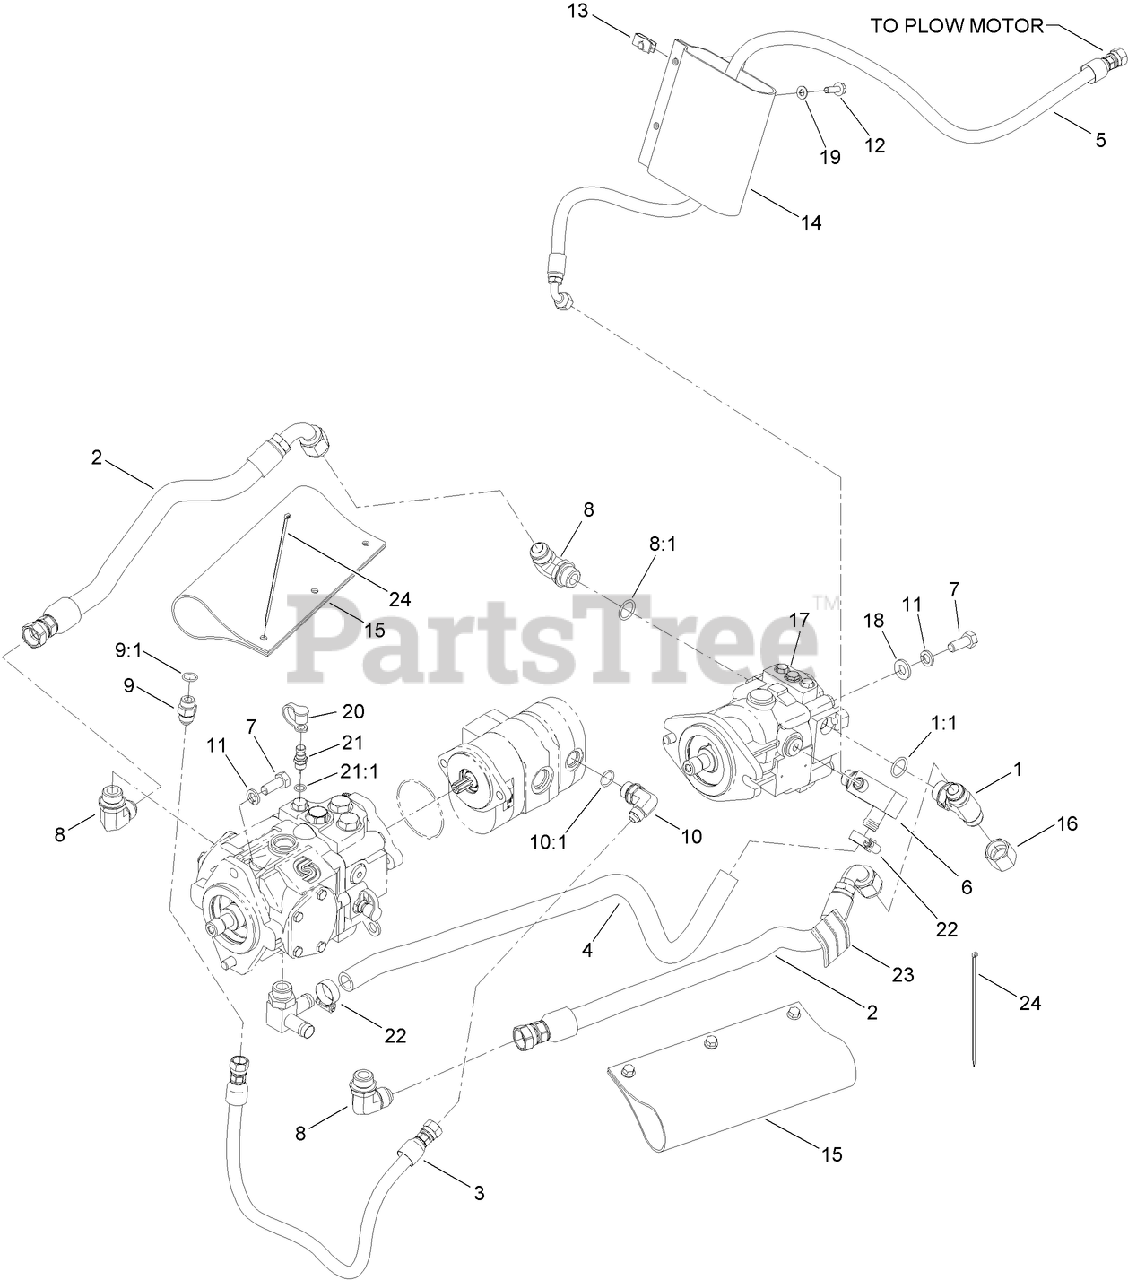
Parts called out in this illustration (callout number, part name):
1	FITTING-BRANCH, TEE
1:1	O-RING
2	HOSE (PUMP TO REG VALVE)
3	HOSE ASM
5	HOSE ASM
6	FITTING-90 DEG (SPECIAL)
7	SCREW-HH
8	FITTING-ELBOW, 90 DEG
8:1	O-RING
9	FITTING-STRAIGHT
9:1	O-RING
10	FITTING-90 DEG
10:1	O-RING
11	WASHER-LOCK
12	SCREW-HHF
14	BOOT-HOSE
15	BOOT-HOSE
17	HYD PISTON MOTOR ASM
19	WASHER-PLAIN
20	CAP-DUST
21	FITTING-DIAGNOSTIC
21:1	O-RING
22	CLAMP-HOSE
23	PROTECTOR-HOSE
24	TIE-CABLE
